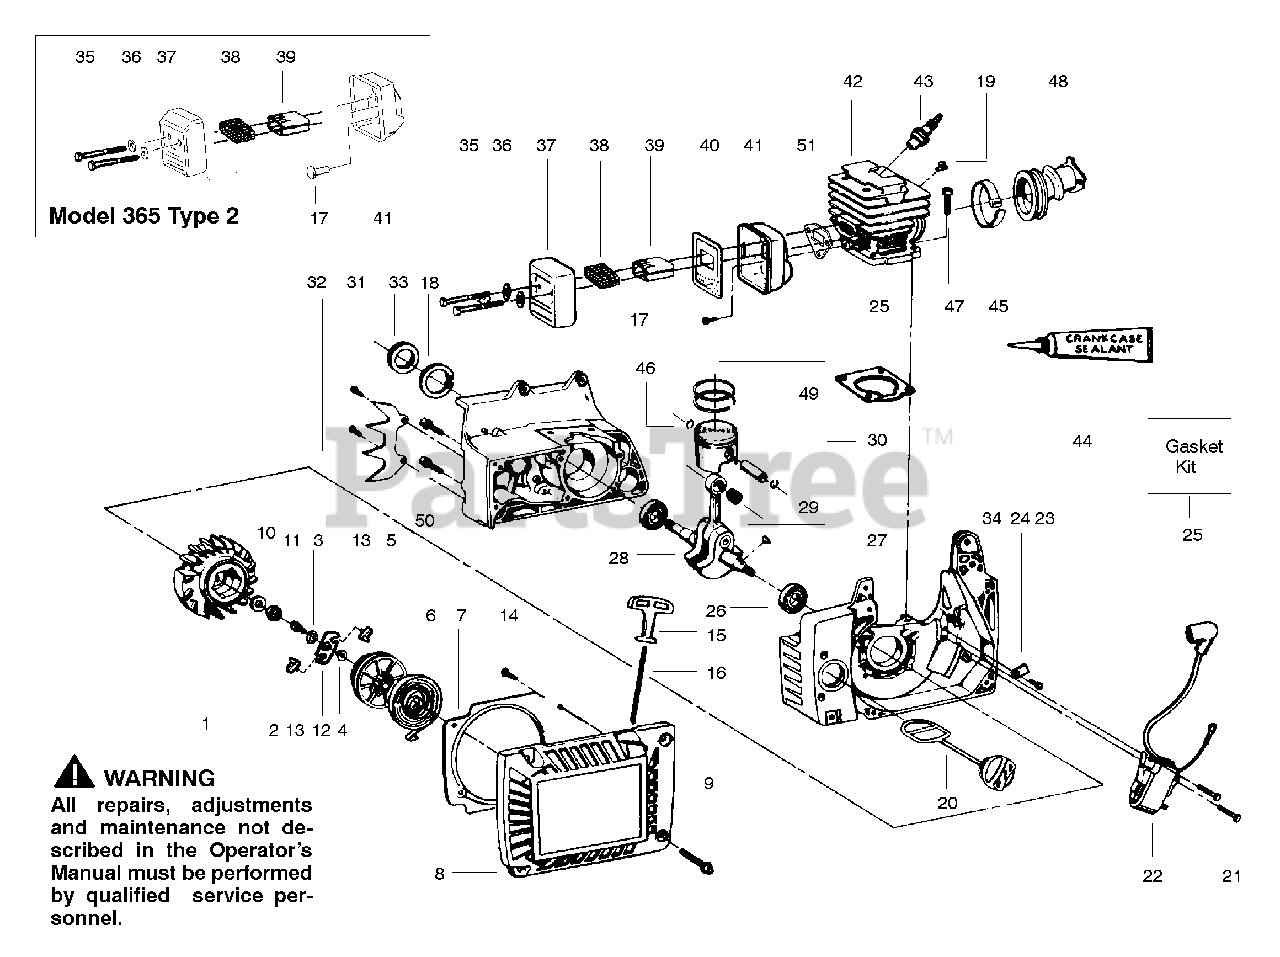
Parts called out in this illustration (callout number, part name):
1	Flywheel
4	Retainer-Starter Pulley
5	Starter Pulley
6	Spring-Starter Pulley
7	Baffle Plate
8	Fan Housing Ass'y.
9	Screw
10	Washer-Conical
12	Starter Cam
13	Starter Dog
14	Screw
15	Starter Handle
16	Rope Kit
20	Oil Cap Ass'y.
21	Screw
22	Ignition Module
25	Engine Gasket Set
26	Crankshaft Bearing
27	Flywheel Key
28	Crankshaft/Rod Ass'y.
29	Piston Pin Bearing
30	Piston Kit Model 336
30	Piston Kit Model 365
33	Crankshaft Seal
34	Crankcase Ass'y. Model 336
34	Crankcase Ass'y. Model 365
35	Screw Model 336 & 365 (Type 1)
35	Screw Model 365 Type 2
37	Muffler Cover Model 336
37	Muffler Cover Model 365 Type 1
37	Muffler Cover Model 365 Type 2
38	Spark Arrestor Screen Model 336
38	Spark Arrestor Screen Model 365 Type 1
38	Spark Arrestor Screen Model 365 Type 2
39	Muffler Diffuser Model 336
39	Muffler Diffuser Model 365 Type 1
39	Muffler Diffuser Model 365 Type 2
40	Muffler Baffle Plate Model 336
40	Muffler Baffle Plate Model 365 Type 1
41	Muffler Body Model 336
41	Muffler Body Model 365 Type 1
41	Muffler Body Model 365 Type 2
42	Cylinder Model 336
42	Cylinder Model 365
43	Spark Plug Model 336
43	Spark Plug Model 365
45	Clamp Ass'y.
46	Retainer
48	Carb. Adapter
49	Piston Ring Model 336
49	Piston Ring Model 365
51	Muffler Gasket
